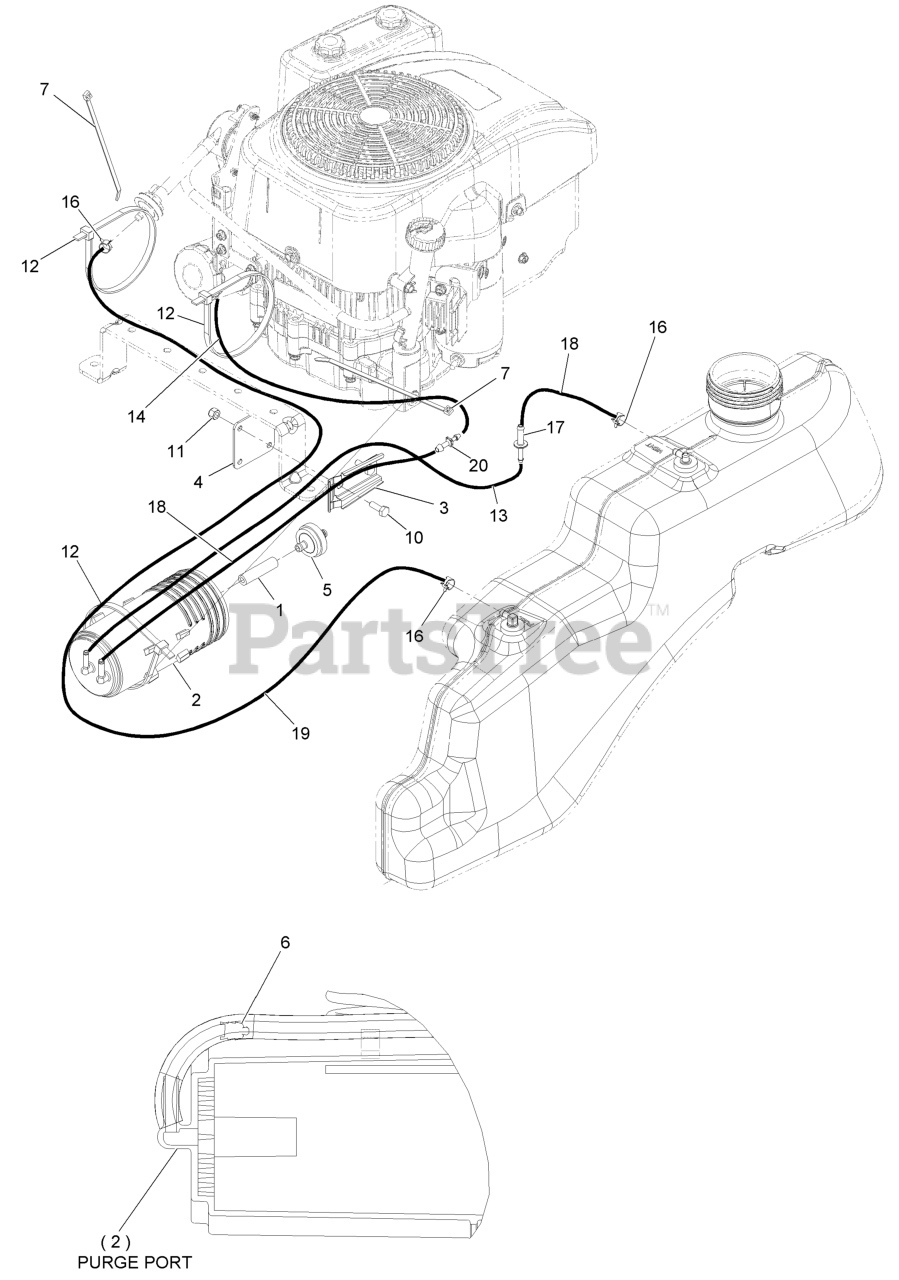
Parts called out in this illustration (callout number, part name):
1	HOSE-FUEL
2	CANISTER-CARBON, 800CC
3	BRACKET-CANISTER, CARBON
4	PLATE-ADAPTER
5	FILTER-FUEL, INLINE
6	CARTRIDGE-VALVE, CHECK
7	TIE-CABLE
10	SCREW-HH
11	NUT-LOCK, NI
12	TIE-CABLE
14	Hose-Fuel (.188 X .406 X 40.00)
16	CLAMP-HOSE
17	ADAPTOR-ORIFICE
18	HOSE-FUEL
19	HOSE-FUEL
20	FITTING-STRAIGHT
